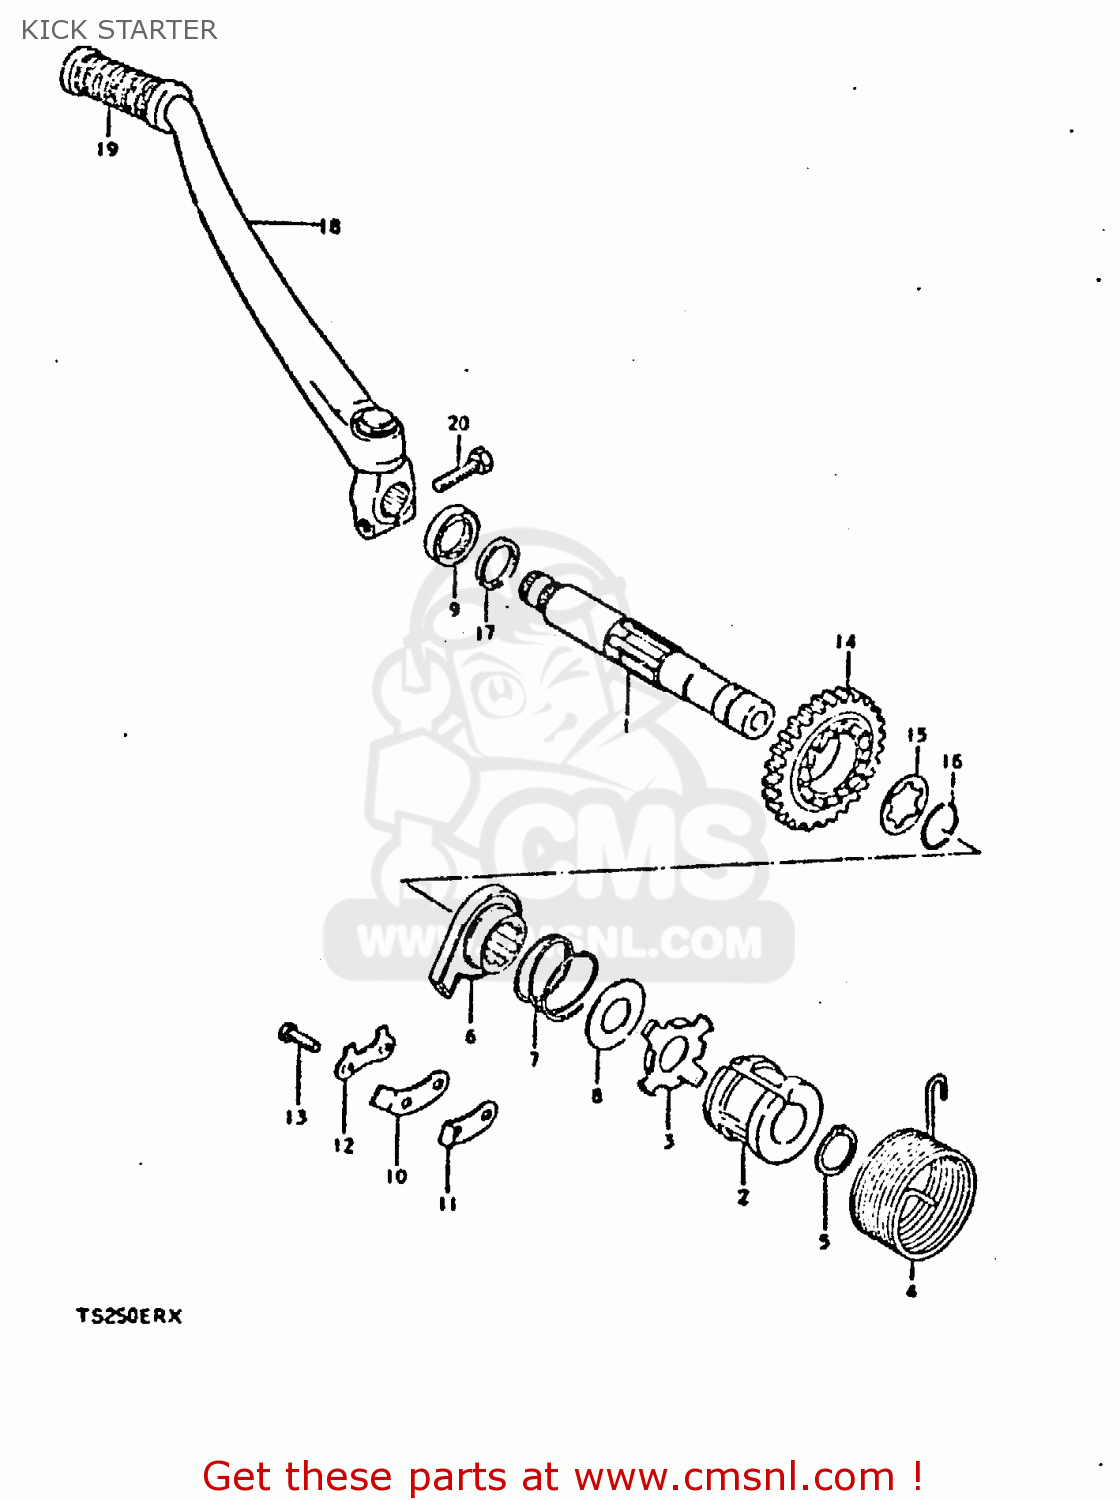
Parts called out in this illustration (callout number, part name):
1	SHAFT,KICK STARTER
2	GUIDE,KICK SHAFT SPRING
3	HOLDER,KICK SHAFT SPRING
4	SPRING
5	CIRCLIP
6	STARTER,KICK
7	SPRING
8	WASHER
9	SEAL,OIL(20X37X7)
10	GUIDE,KICK STARTER
11	STOPPER,KICK STARTER
12	WASHER
13	BOLT, UPPER
14	GEAR,KICK STARTER DRIVE
15	WASHER,LOCK
16	CIRCLIP
17	SPACER(20X28X4.5)
18	LEVER ASSEMBLY,KICK STARTER
19	RUBBER,KICK STARTER PEDAL
20	BOLT
